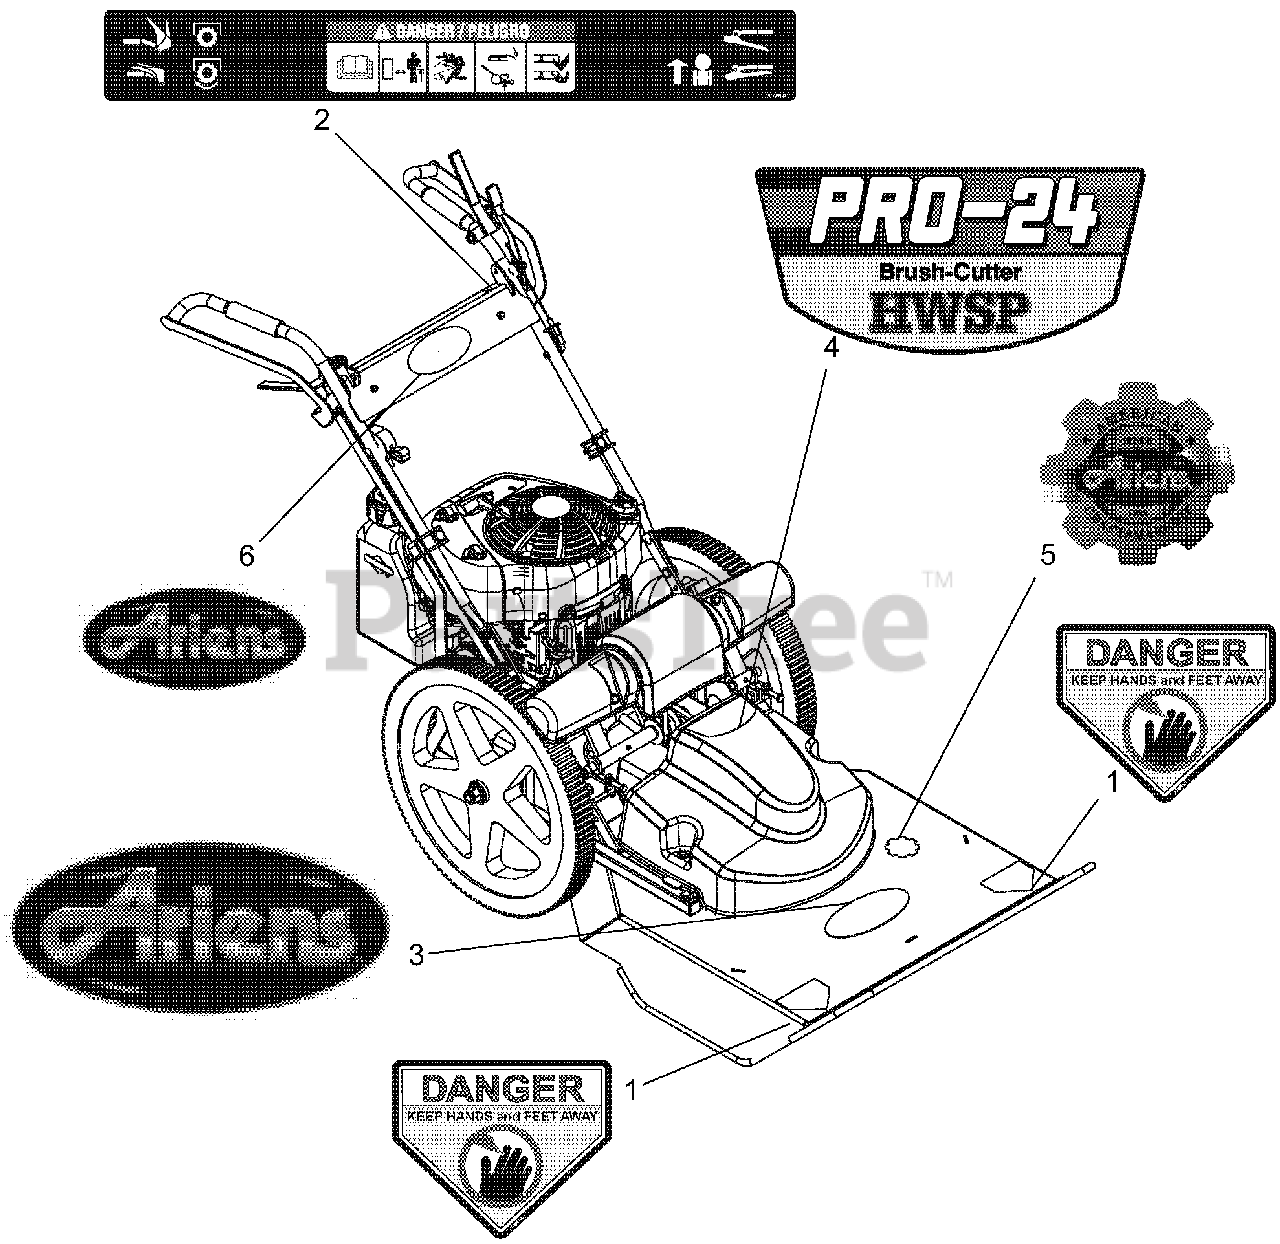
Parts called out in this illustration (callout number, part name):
1	DECAL, DANGER
2	DECAL-OPER./DANGER 24BRUSHCUT
3	DECAL, ARIENS JEWEL
4	DECAL, BRUSHCUTTER 24" ARIENS
5	DECAL, ARIENS HERITAGE-SMALL
6	DECAL, ARIENS JEWEL (LARGE)
